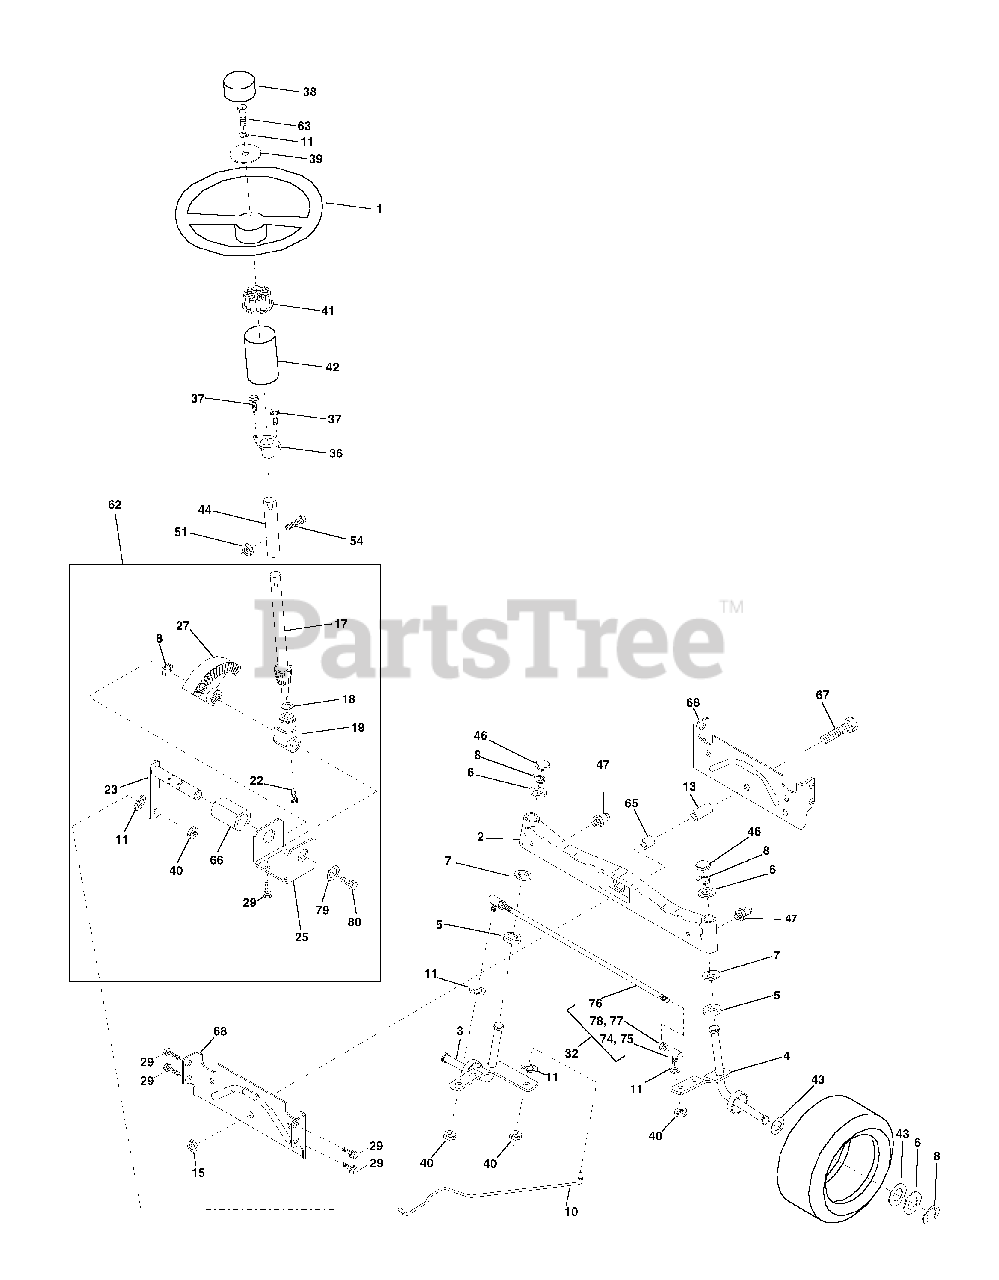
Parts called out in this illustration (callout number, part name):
1	Wheel Steering
2	Axle Front Casting Machined
3	Spindle Asm Cast LH
4	Spindle Asm Cast RH
5	Bearing Race Thrust Harden
6	Washer 25/32 X 1-5/8 X 16 Ga
7	Washer 27/32 X 1-1/4 X 16 Ga
8	Ring Klip #t5304-75
10	Link Drag Extended Cast
11	Washer Lock Hvy Hlcl Spr 3/8
13	Bearing Axle STLT/GT
15	Nut Lock Flange 5/8-11 Unc
17	Shaft Asm Strg Private Label
18	Washer Thrust 515x 750x 033
19	Support Shaft
22	Screw Hex Wshhd Torx
23	Shaft Asm Pittman
25	Bracket Steering
27	Gear Sector 22 Teeth
29	Screw Thdrol 3/8-16x3/4 Ty-tt
32	Rod Tie
36	Bushing Strg
37	Screw TT #32.5 x 5 x 3/8 Flange
38	Cap Wheel Steer
39	Washer 13/32 x 2-3/8 x 8 Ga.
40	Nut Lock Center 3/8-24 Unf
41	Adaptor Wheel Strg
42	Boot Dash Steering
43	Washer 25/32 X 1 1/4 X 16 Ga
44	Extension Steering Non-adjust
46	Cap Spindle Fr Top Blk
47	Fitting Grease
51	Nut Lock Hex W/Ins 5/16-18 UNC
54	Bolt Fin Hex 5/16-18 UNC x 1-1/4
62	Steering Assembly
63	Bolt Fin Hex 3/8-16 UNC x 1 Gr. 5
66	Bearing Arm Pittman
67	Bolt Fin Hex 5/8-11 UNC x 2-3/4
68	Brace, Axle
74	Joint Asm Ball Rh
75	Joint Asm Ball Lh
76	Rod Tie Ball J Adj
77	Nut Hex Jam 3/8-24 Unf Lh
78	Nut Hex Jam 3/8-24 Unf
79	Washer 13/32 x 1-1/4 x 12 Ga.
80	Bolt Hex Nylon 3/8-16 x 3/4
